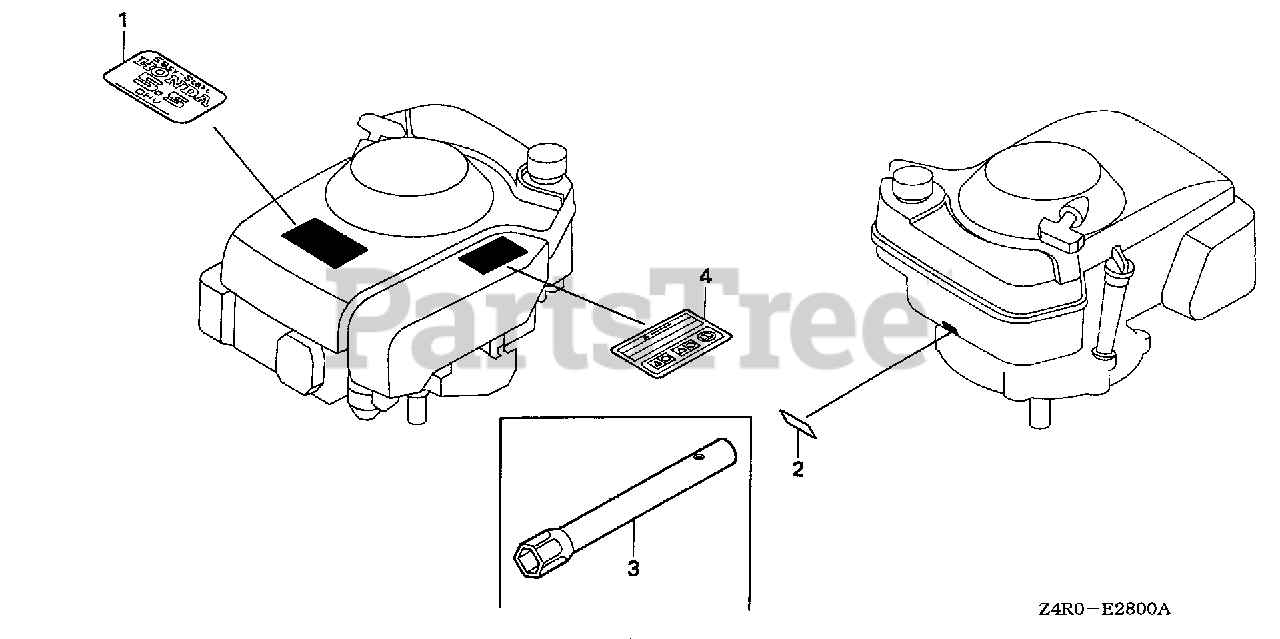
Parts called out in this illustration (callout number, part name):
1	EMBLEM (5.5)
2	MARK, TYPE (N12)
3	WRENCH, BOX (P21)
4	MARK, OPERATOR CAUTION (ENGLISH)(MADE IN U.S.A.)
4	MARK, OPERATOR CAUTION (FRENCH)(MADE IN U.S.A.)
4	MARK, OPERATOR CAUTION
